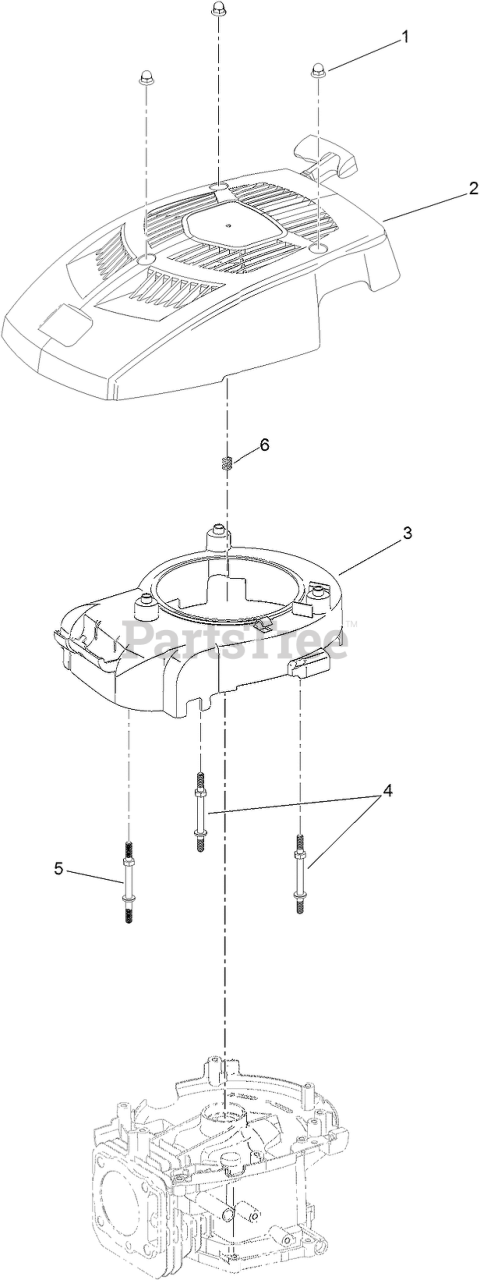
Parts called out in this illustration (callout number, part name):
1	NUT-ACORN
2	RECOIL SHROUD ASM
3	SHROUD-FAN
4	STUD-SHROUD
5	STUD-SHROUD
6	SPRING-COMPRESSION, RECOIL
